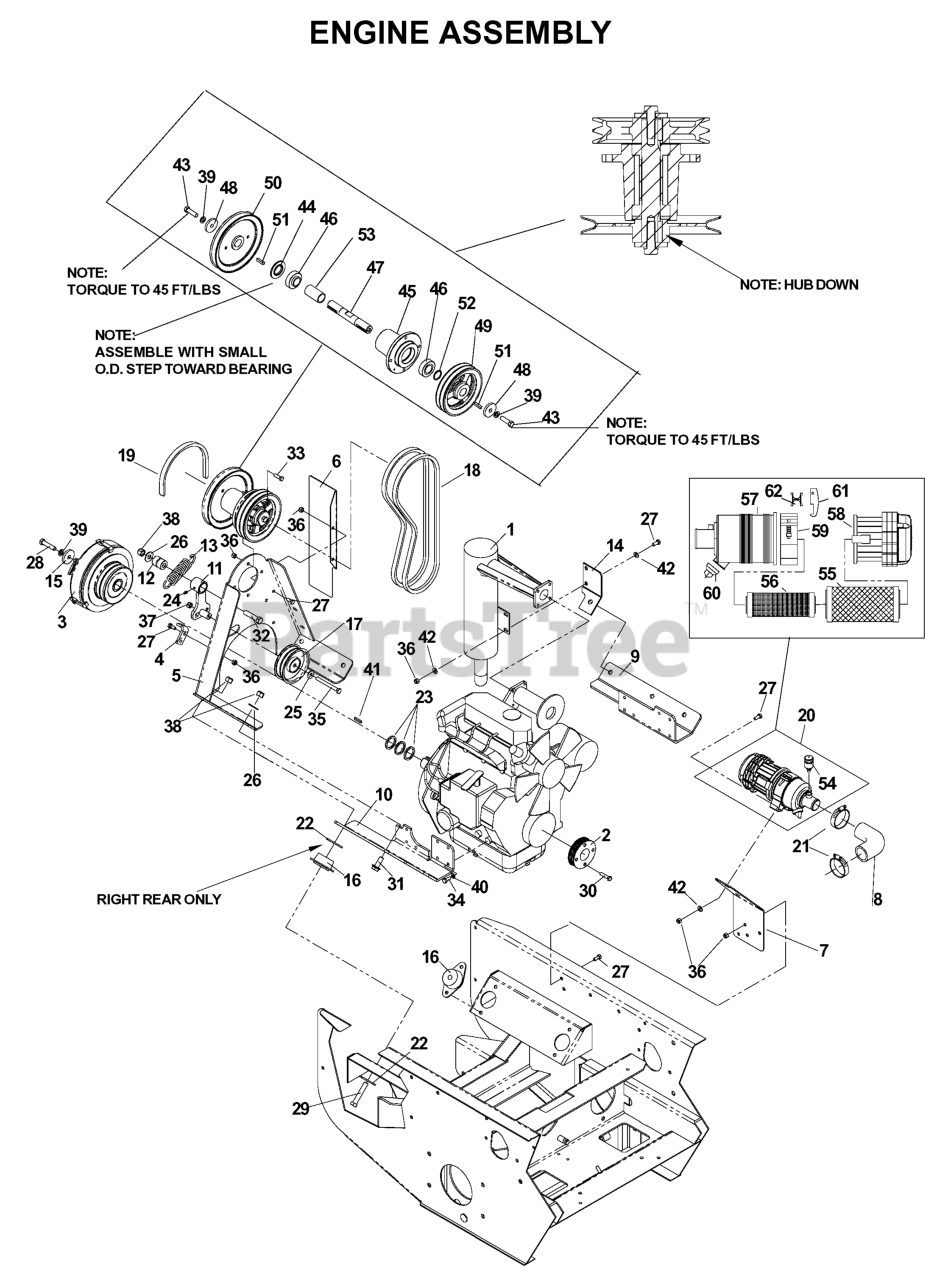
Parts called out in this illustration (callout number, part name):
1	MUFFLER ASSY
2	ENGINE SHEAVE
3	CLUTCH
4	RESTRAINT
5	JACKSHAFT MOUNT WELDMENT
6	HEAT SHIELD
7	MOUNTING BRACKET
8	AIR FILTER HOSE
9	ENGINE MOUNT-LT
10	ENGINE MOUNT-RT
11	ARM WELDMENT
14	MUFFLER MT BLACK PAINTED
15	SPINDLE WASHER
17	IDLER, PRIMARY
18	ENGINE BELT, PRIMARY
19	ENGINE, BELT MULE
20	AIR FILTER ASSY
21	CLAMP, AIR HOSE
22	ISOLATOR WASHER
23	BUSH 1-1/8 X 10 GA ZD
24	ZERK
25	WASHER 3/8 SAE FLAT
26	WASHER 1/2 FLAT
27	HCS 5/16C X 3/4
28	BOLT 7/16F X 2 1/2
29	HCS 1/2C X 2 3/4
30	HTB M8-1.125 X 25MM
31	HCS 1/2C X 1 1/4 SERRATED HEAD
32	HEX SCREW 1/2-13 X 2.5" GR 5
33	HCS 5/16C X 1
35	HCS 3/8-16 X 3-1/2 GR5 ZD
36	NUT 5/16 NYLOC
37	NUT 3/8-16 NYLOC
38	NUT 1/2-13 HEX NYLOC ZD
39	WASHER 7/16 LOCK
40	WASHER.LOCK.HVY.HLCL.SPR.5/16
41	KEY 1/4" SQ X 1 7/8"
42	WASHER 5/16 FLAT
43	HCS 7/16F X 1 1/2
44	COMBO SPACER
45	HOUSING, DIE CAST
46	BEARING
48	SPINDLE WASHER
51	KEY 1/4 SQ X 1 1/8
52	BUSHING.MACHINE.18.GAUGE
55	AIR FILTER
56	SAFETY ELEMENT
57	BODY, STRAIGHT
58	PRECLEANER ASM
59	MOUNTING BRACKET
539106327	STUB SHAFT
